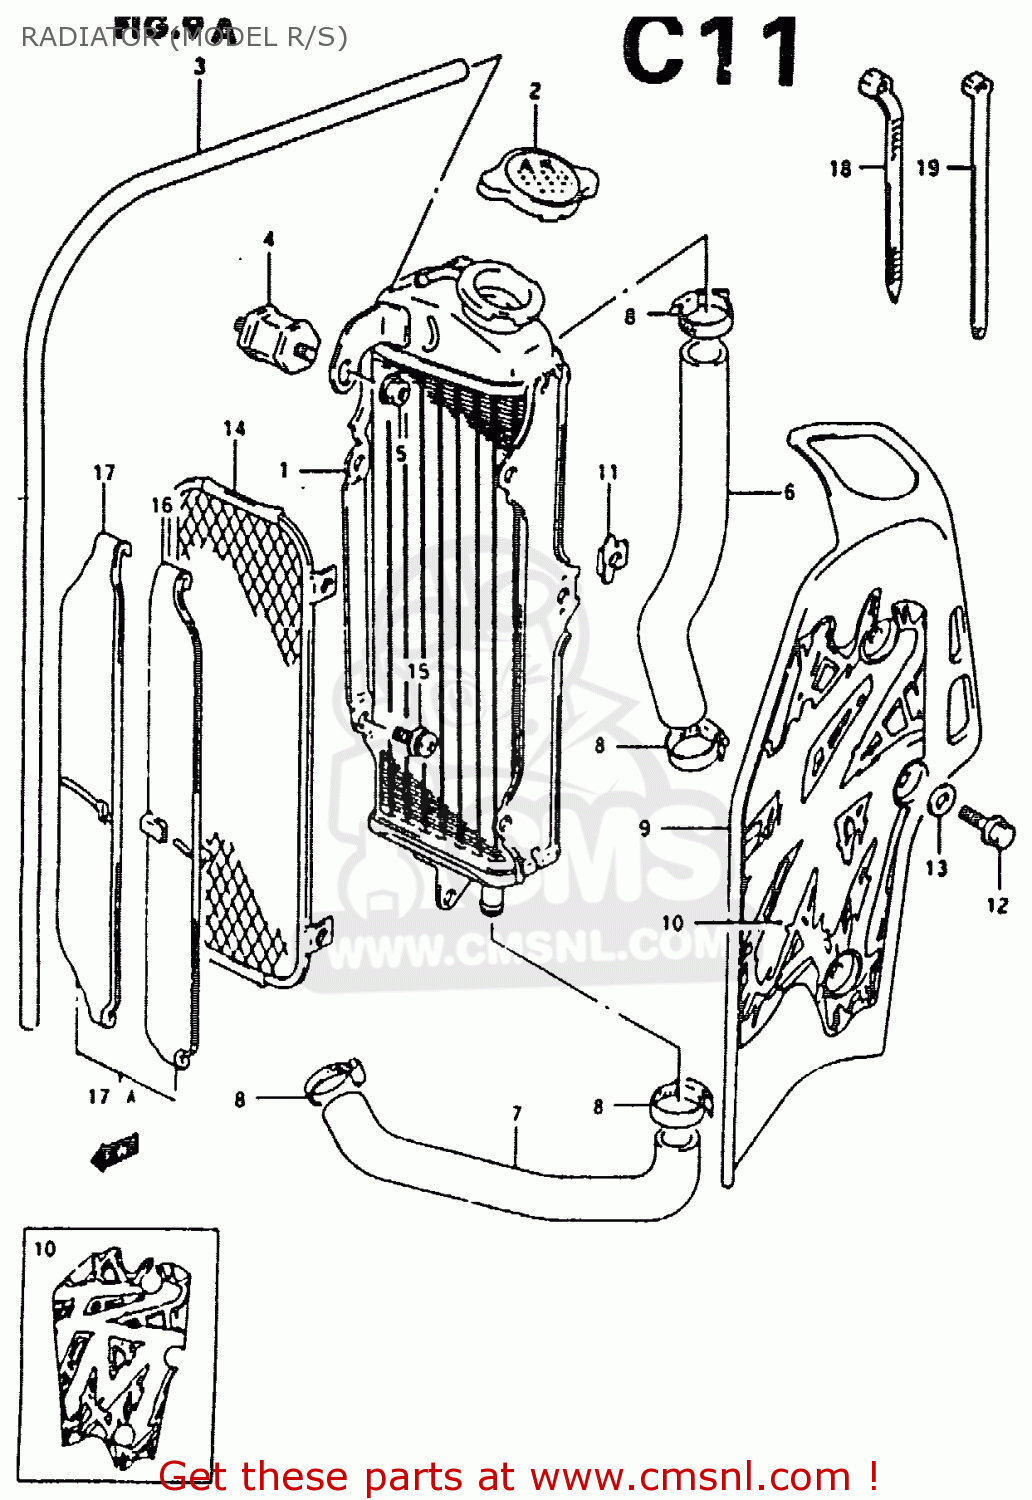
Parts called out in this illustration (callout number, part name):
1	RADIATOR COMP,WATER
2	CAP,RADIATOR
3	HOSE (5X8X600)
4	BOLT,RADIATOR CUSHION
5	NUT
6	HOSE,RADIATOR INLET
7	HOSE,RADIATOR OUTLET
8	CLAMP
9	COVER,RADIATOR
10	EMBLEM,RADIATOR COVER
11	PLATE,RADIATOR COVER FITING
12	BOLT
13	WASHER(6.5X18X1)
14	BUMPER,RADIATOR
15	SCREW
16	LOUVER,RADIATOR,OUTER (
17	SCREW(6X14)
17A	LOUVER,RADIATOR (BLACK)
18	BOLT
19	CLAMP
20	BUMPER,RADIATOR
21	SCREW
22	WASHER,LOCK
23	WASHER
24	LOUVER,RADIATOR
25	LOUVER,RADIATOR
26	CLAMP(L:165)
27	CLAMP
